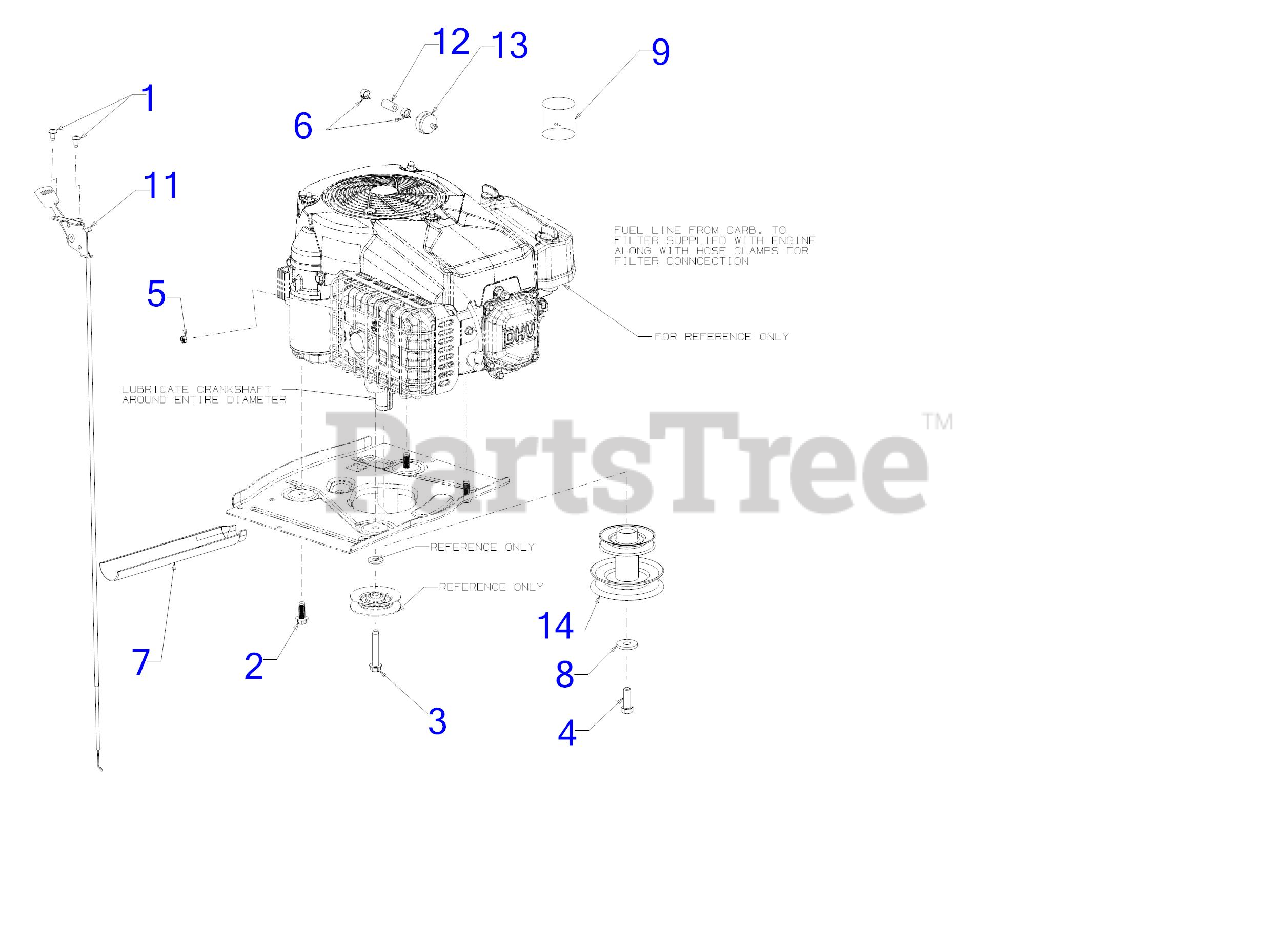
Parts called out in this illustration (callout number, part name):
1	SCREW 1/4-20 x .500
2	SCREW 3/8-16 x 1
3	SCREW 3/8-16 x 2.250
4	SCREW 7/16-20 x 1.250 GR5
5	HEX NUT
6	HOSE CLAMP 1/20
7	OIL DRAIN SLEEVE
8	FLAT WASHER .445 x 1.248 x .170
9	OIL:SAE 10W30
11	THROTTLE CABLE 31" x 1.1
12	FUEL HOSE LOW PERMEATION
13	FUEL FILTER
14	ENGINE PULLEY
